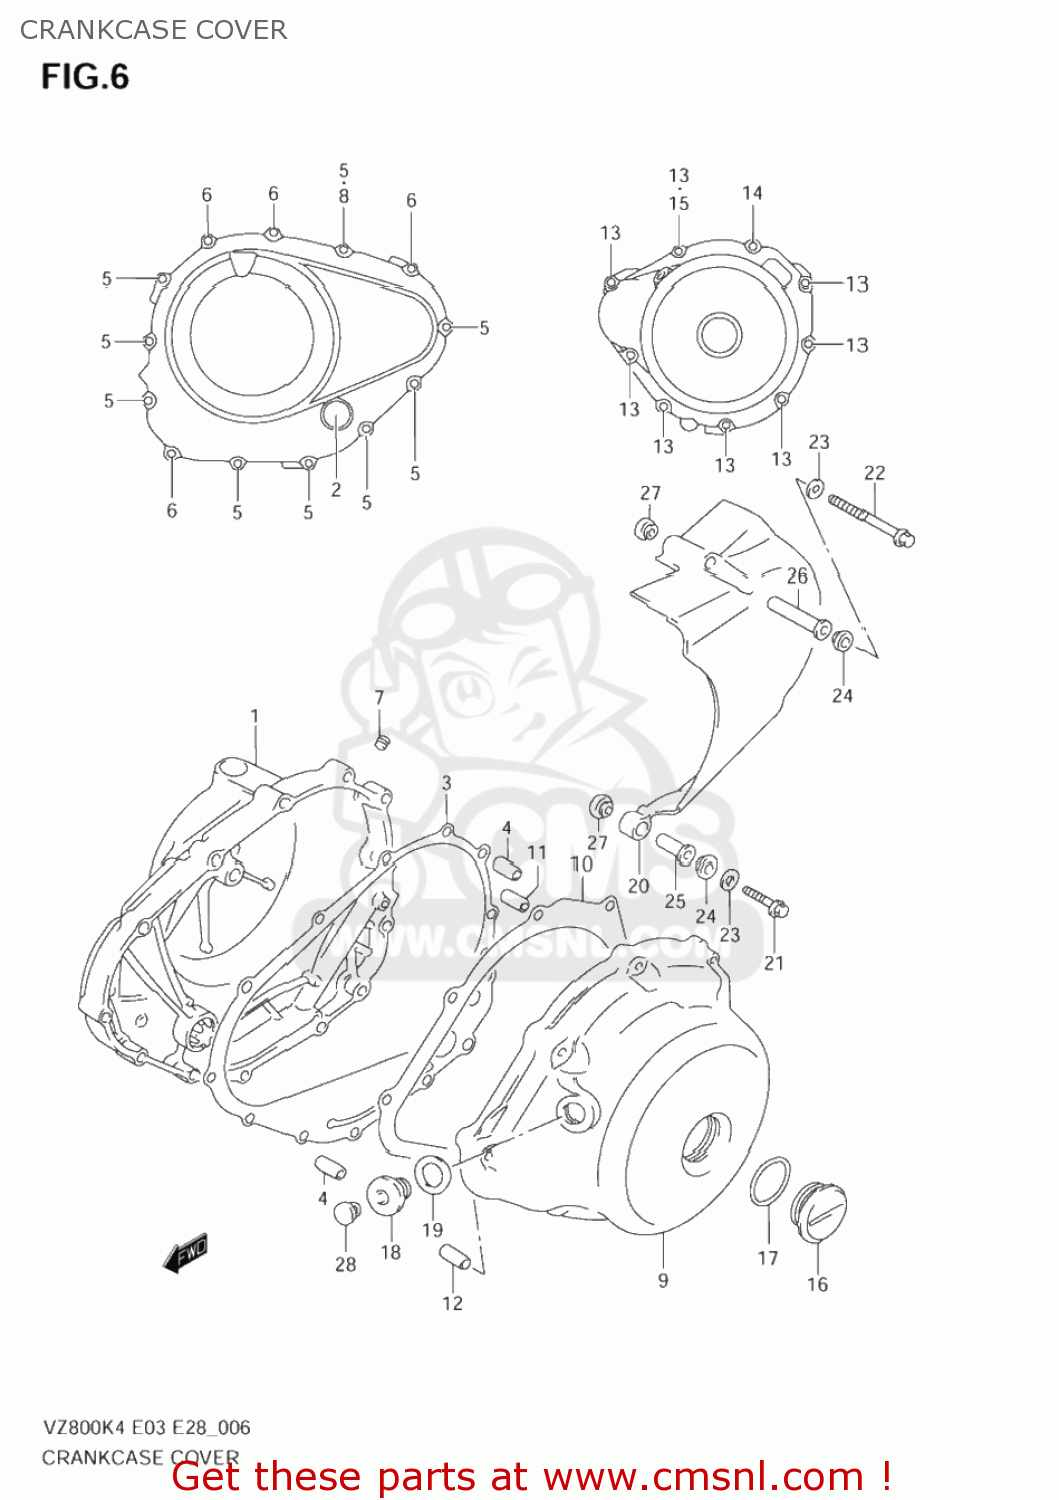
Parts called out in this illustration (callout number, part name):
1	COVER,CLUTCH
2	LENS,OIL LEVEL CHECK
3	GASKET,CLUTCH COVER
4	PIN
5	BOLT
6	BOLT
7	PLUG(1/8PT,H:5.5)
8	GASKET(5.8X13X1.2) (NAS)
9	COVER,MAGNETO
10	GASKET,CLUTCH COVER
11	PIN(8.4X11X20)
12	PIN
13	BOLT
14	BOLT
15	GASKET(5.8X13X1.2) (NAS)
16	Chrome Crankshaft Plug
17	O RING(D:3.1,ID:32.7)
18	PLUG,14X12
19	GASKET(13.8X18.8X4.8) (NAS)
20	COVER,ENGINE SPROCKET
21	BOLT
22	BOLT
23	WASHER(6.5X14X1.6)
24	WASHER(8.7X15X2.1)
25	SPACER(6.5X9X19.4)
26	SPACER(6.5X9X47.1)
27	WASHER(8.7X16X5)
28	CAP(OD:12)
